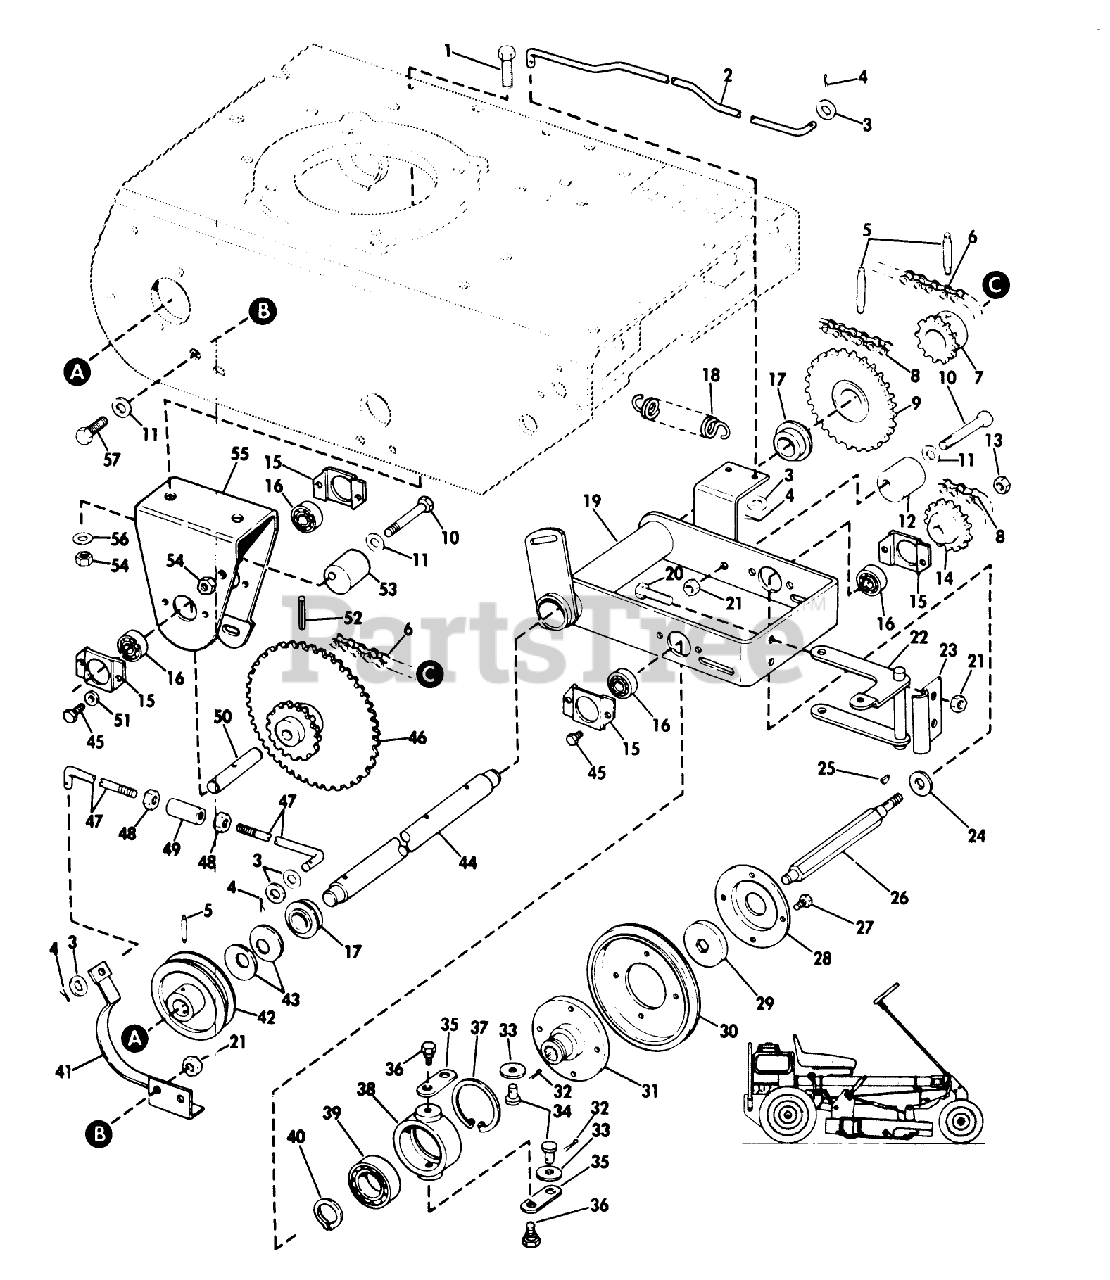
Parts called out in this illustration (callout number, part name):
13	LOCKNUT
30	DRIVE WHEEL
48	STOP NUT
54	LOCKNUT
